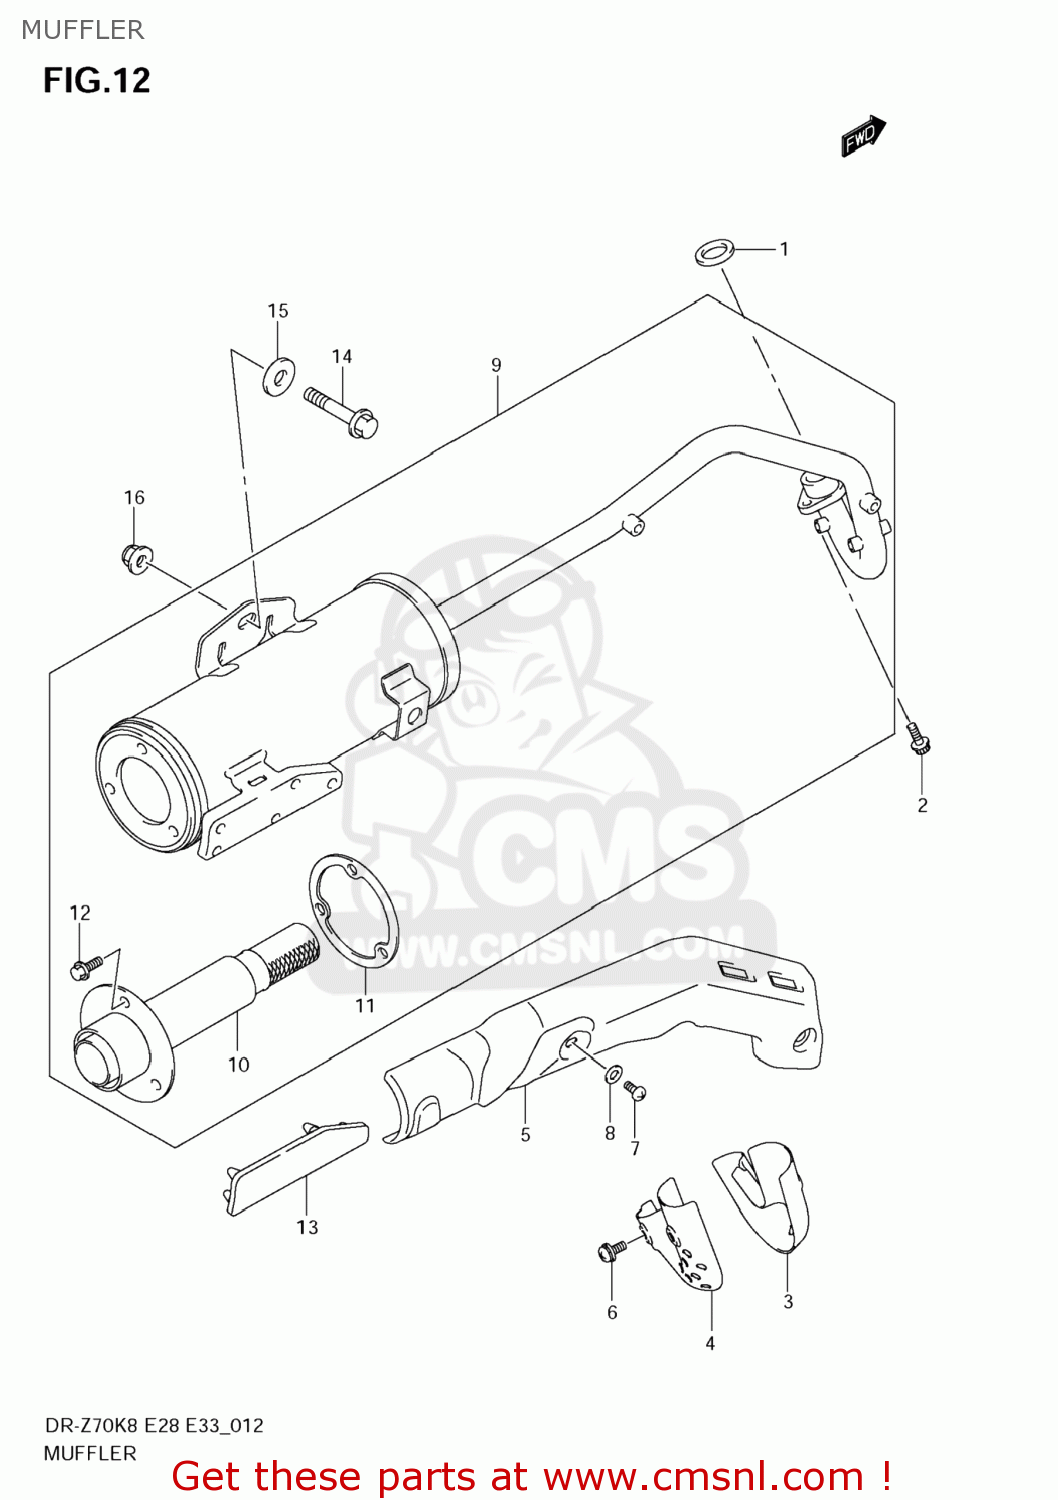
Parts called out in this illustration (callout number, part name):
1	GASKET,EXHAUST PIPE (NAS)
2	BOLT
3	COVER,EXHAUST PIPE
4	COVER,EXHAUST PIPE INNER
5	COVER,EXHAUST PIPE NO.2
6	SCREW
7	BOLT(5X10)
8	WASHER
9	BODY,MUFFLER
10	ARRESTER
11	GASKET,ARRESTER (NAS)
12	BOLT(6X12)
13	PROTECTOR,HEAT GUARD
14	BOLT(8X40)
15	WASHER(8.5X22X2)
16	NUT
